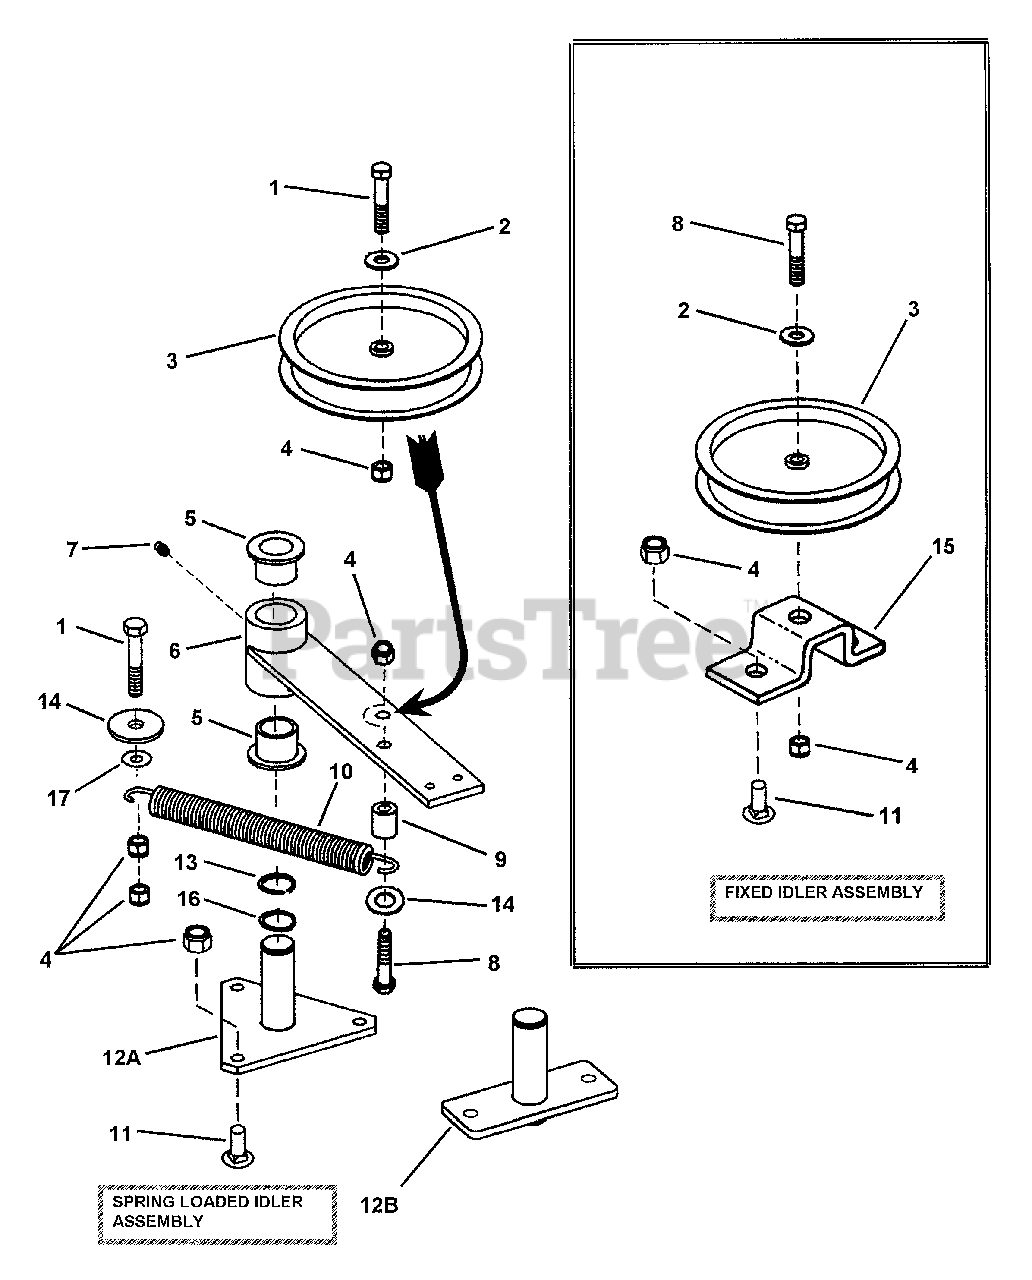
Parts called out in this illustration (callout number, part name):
1	BOLT, 3/8-16 X 2, GD5, CZ
2	WASHER, 3/8" USS
3	PULLEY, Idler 5-1/2" O.D.
4	NUT, 3/8-16 HEX NYLON LOCK
5	BUSHING
6	ARM, Idler (Weldment)
7	FITTING, Lube 1/4-28 Straight
8	SCREW, 3/8-16 x 1-3/4" Hex Head Cap, Grade 5
9	SPACER, .50 I.D. x.75 O.D. x .83
10	SPRING, Extension
11	BOLT, 3/8-16 x 1" Square Neck Carriage, Grade 5
12A	WELDMENT, Tri-Mount Idler Pivot (61" Deck only)
12B	WELDMENT, Idler Pivot (52" Deck only)
13	RING, 1" External-Retaining
14	WASHER, .406 x 1.5 x .120 Yellow Zinc
15	STAND, Fixed Idler
16	WASHER, 1.031 x 1.25
17	RETAINER, 3/8" Bolt
